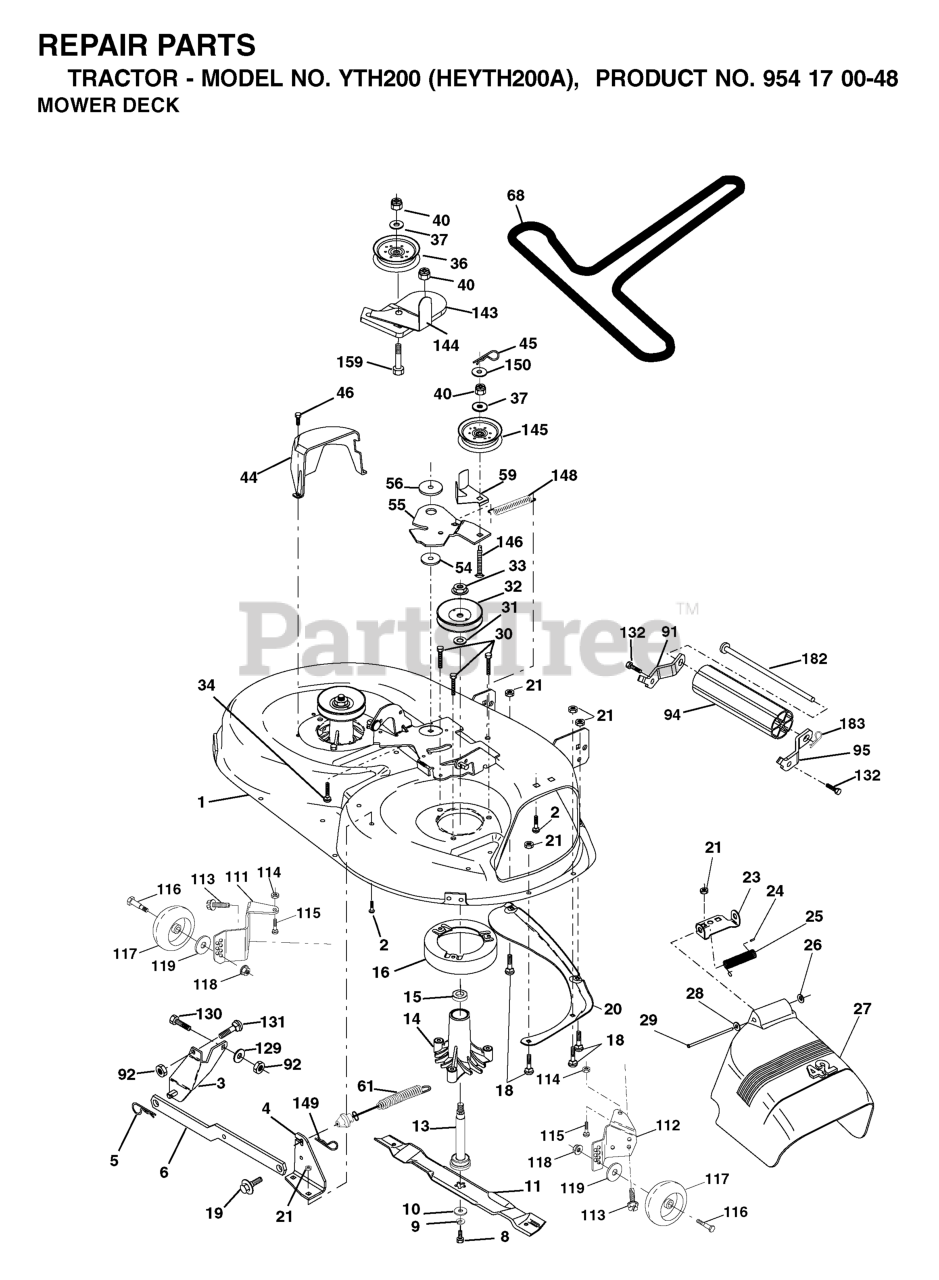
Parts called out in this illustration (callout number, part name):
1	42" DECK KIT
2	RP BOLT 5/16-18 X3/4 ZN/YEL GR
3	BRKT ASM SWAY BAR
4	BRACKET SWAY BAR 42" DECK
5	RETAINER-SPRNG RB
6	BAR SWAY DECK
8	BLADE BOLT
9	LOCKWASHER
10	WASHER.BLADE
11	Blade Mower 42" High Perf.
13	SHAFT ASM VENT
14	HOUSING.MANDREL.VENTED (MACHD)
16	STRIPPER.MANDREL.ROUND.BLACK
18	BOLT
19	BOLT SHD 5/16-18
20	BAFFLE.VORTEX
21	LOCKNUT
23	BRKT, DEFL. MOWER
24	CAP-SLEEVE LT
25	SPRING TORSION
26	NUT PUSH M
27	SHIELD DEFLECTOR
28	Washer 11/32 x 5/8 x 16 Ga SD
29	ROD.HINGE
30	SCREW, WASHER HEAD
31	WASHER
32	PULLEY/MANDREL
33	NUT, FLG TOPLOCK 9/16"
36	FLAT IDLER PULLEY
37	WASHER
44	GUARD MANDREL LH BLACK
45	RETAINER M
46	SCREW.1/4-20X5/8
54	HARDENED WASHER
55	ARM IDLER 42" MOWER LT/YT
56	SPACER.RETAINER.MOWER
59	GUARD, BELT
61	SPRING EXT ELEC CLUTCH
91	BRACKET ASM NOSEROLLER LH
92	NUT
94	NOSE ROLLER
95	BRACKET ASM NOSEROLLER RH
111	BRACKET, WHEEL
112	BRACKET, WHEEL
113	Screw Tapping 3/8-16 x .625
114	NUT
115	BOLT.CARR.5/16-18X5/8.SHORT
116	BOLT M
117	WHEEL.GAUGE.STANDARD
118	LOCKNUT
119	WASHER.5/16.FLAT.STE.STD.
129	WASHER
131	BOLT D
132	SCREW 3/8-16X3/4
143	BRACKET, ARM IDLER
144	DNO KEEPER.BELT.42".CLUTCH.CBL
145	PULLEY
146	BOLT, CARRIAGE IDLER BLACK
148	IDLER RETURN SPRING
149	SPRING.RETAINER.YELLOW.ZINC
160	SCREW 3/8-16X3/4
182	ROD ROLLER NOSE STANDARD
183	SPRING RETAINER
